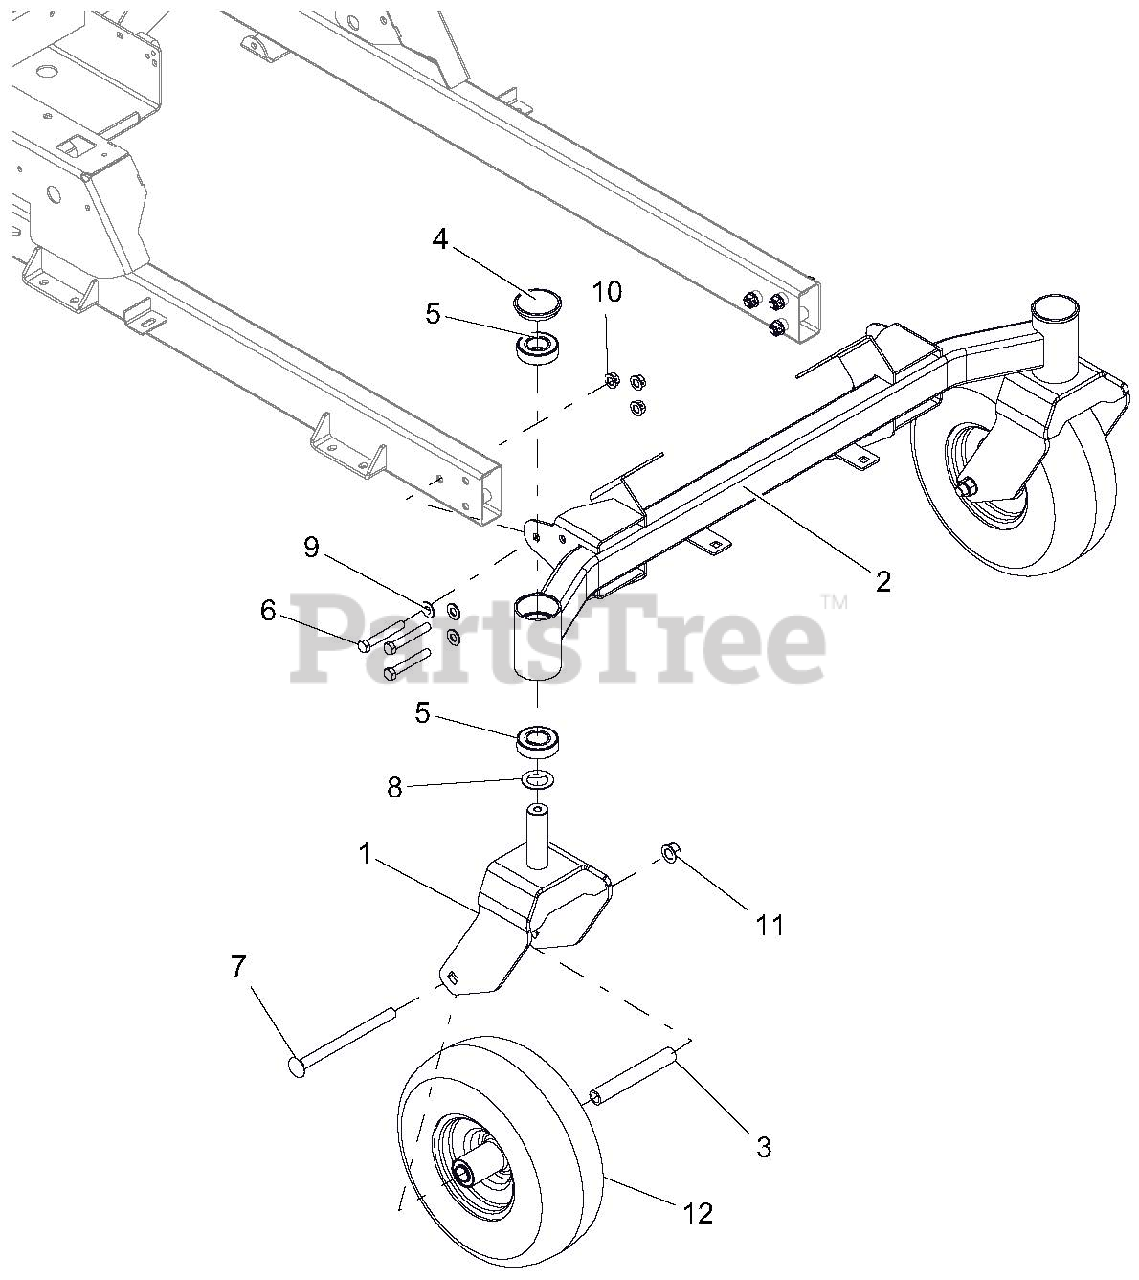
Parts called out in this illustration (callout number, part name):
1	WLDMT, CASTER FORK
2	WLDMT, AXLE FRONT
3	SPCR, ROLLED WHEEL
4	CAP, DUST
5	BRG-BALL 1.00X2.00X.56
6	BLT-HEX .38-16X2.50 GR8 YWZC
7	BLT-RDHDSQNK .50-13X6.50 G5 Y
8	WSHR, HRD THRS 1.007X1.542X.062
9	WSHR-HDND .406X.812X.075
10	NUT, LK-TOP-FLG .38-16 GRG YWZC
11	NUT, LK-TOP-FLG .50-13 YWZC
12	TIRE/WHEEL, 11 X 4-5
